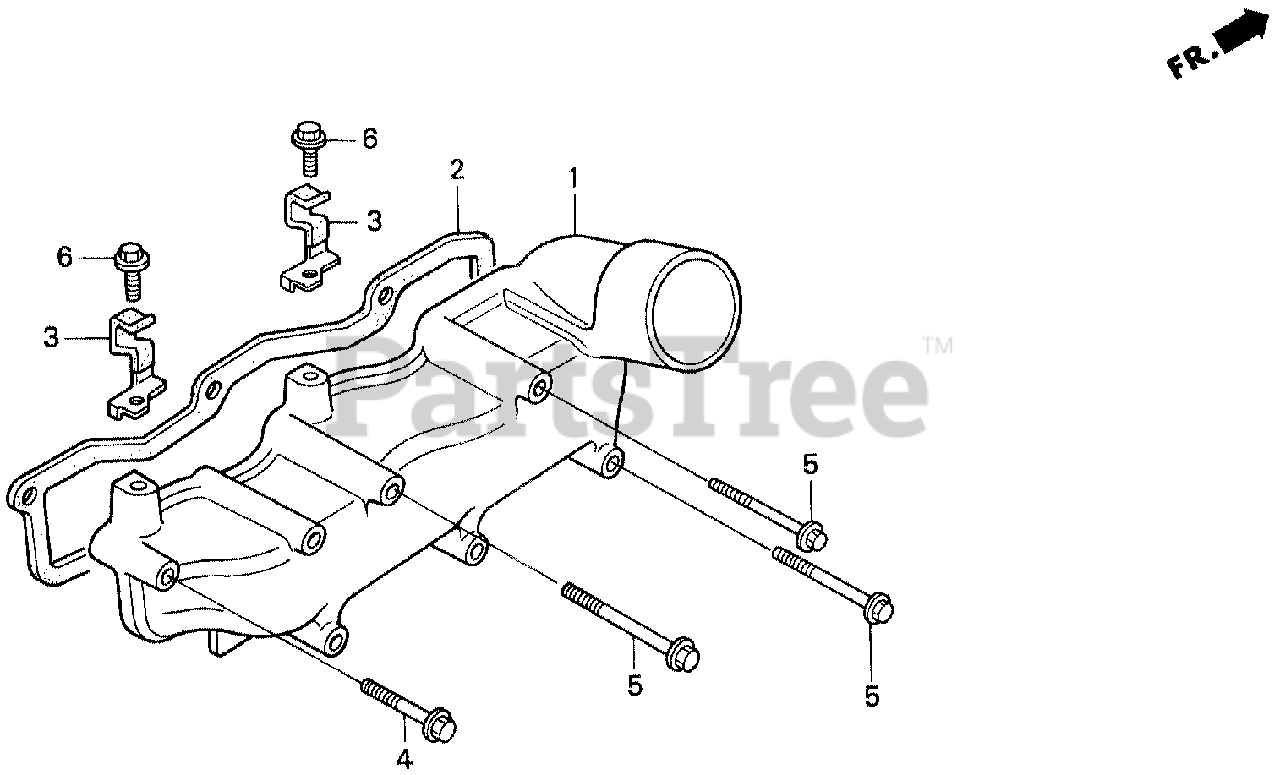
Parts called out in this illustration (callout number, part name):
1	MANIFOLD, IN.
2	GASKET, IN. MANIFOLD (NON-ASBESTOS)
3	CLAMP, WIRE
4	BOLT, FLANGE (6X40)
5	BOLT, FLANGE (6X65)
6	BOLT, FLANGE (6X10)
